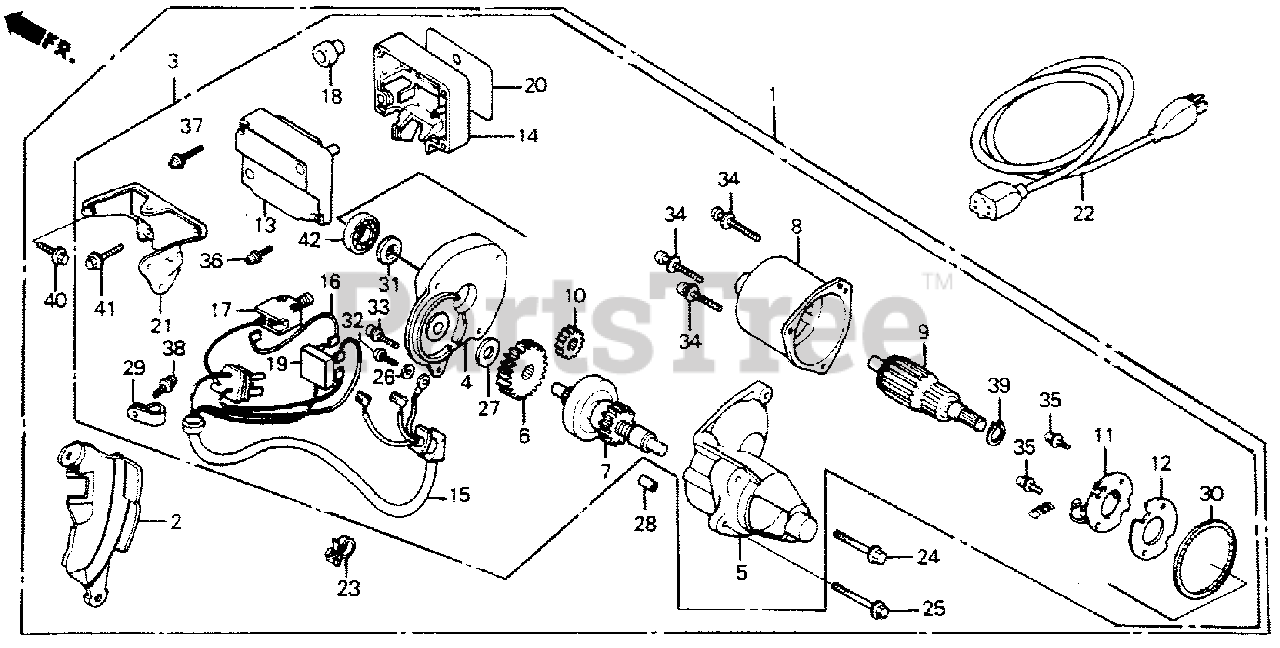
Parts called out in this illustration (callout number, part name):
1	ELECTRIC START KIT (HS55) Use up to Engine SN 2056819.
2	PLATE, SIDE (STARTER MOTOR) Use up to Engine SN 2056819.
3	MOTOR ASSY., STARTER Use up to Engine SN 2056819.
4	HOUSING, CENTER Use up to Engine SN 2056819.
5	HOUSING, PINION Use up to Engine SN 2056819.
6	GEAR, REDUCTION Use up to Engine SN 2056819.
7	CLUTCH Use up to Engine SN 2056819.
8	YOKE Use up to Engine SN 2056819.
9	ARMATURE Use up to Engine SN 2056819.
10	GEAR, DRIVE Use up to Engine SN 2056819.
11	HOLDER ASSY., BRUSH Use up to Engine SN 2056819.
12	SHEET, HOLDER Use up to Engine SN 2056819.
13	COVER Use up to Engine SN 2056819.
14	CASE Use up to Engine SN 2056819.
15	WIRE Use up to Engine SN 2056819.
16	SUB-WIRE Use up to Engine SN 2056819.
17	SWITCH, STARTER Use up to Engine SN 2056819.
18	CAP Use up to Engine SN 2056819.
19	DIODE Use up to Engine SN 2056819.
20	PLATE, CAUTION Use up to Engine SN 2056819.
21	BRACKET, SWITCH BOX Use up to Engine SN 2056819.
22	WIRE, POWER Use up to Engine SN 2056819.
23	HOLDER, STOP SWITCH WIRE Use up to Engine SN 2056819.
24	BOLT, FLANGE (6X32) Use up to Engine SN 2056819.
25	BOLT, FLANGE (6X25) Use up to Engine SN 2056819.
26	WASHER, STAR (4MM) Use up to Engine SN 2056819.
27	WASHER Use up to Engine SN 2056819.
28	PIN, DOWEL (8X10) Use up to Engine SN 2056819.
29	CLIP, CORD (5/16) Use up to Engine SN 2056819.
30	GASKET Use up to Engine SN 2056819.
31	OIL SEAL Use up to Engine SN 2056819.
32	SCREW, PAN (4X6) Use up to Engine SN 2056819.
33	SCREW-WASHER (5X16) Use up to Engine SN 2056819.
34	SCREW-WASHER (5X30) Use up to Engine SN 2056819.
35	SCREW-WASHER (4X12) Use up to Engine SN 2056819.
36	SCREW-WASHER (4X20) Use up to Engine SN 2056819.
37	SCREW-WASHER (4X30) Use up to Engine SN 2056819.
38	SCREW-WASHER (5X16) Use up to Engine SN 2056819.
39	CIRCLIP (OUTER) (12MM) Use up to Engine SN 2056819.
40	BOLT, FLANGE (6X10) Use up to Engine SN 2056819.
41	BOLT, FLANGE (6X40) Use up to Engine SN 2056819.
42	BEARING, RADIAL BALL Use up to Engine SN 2056819.
